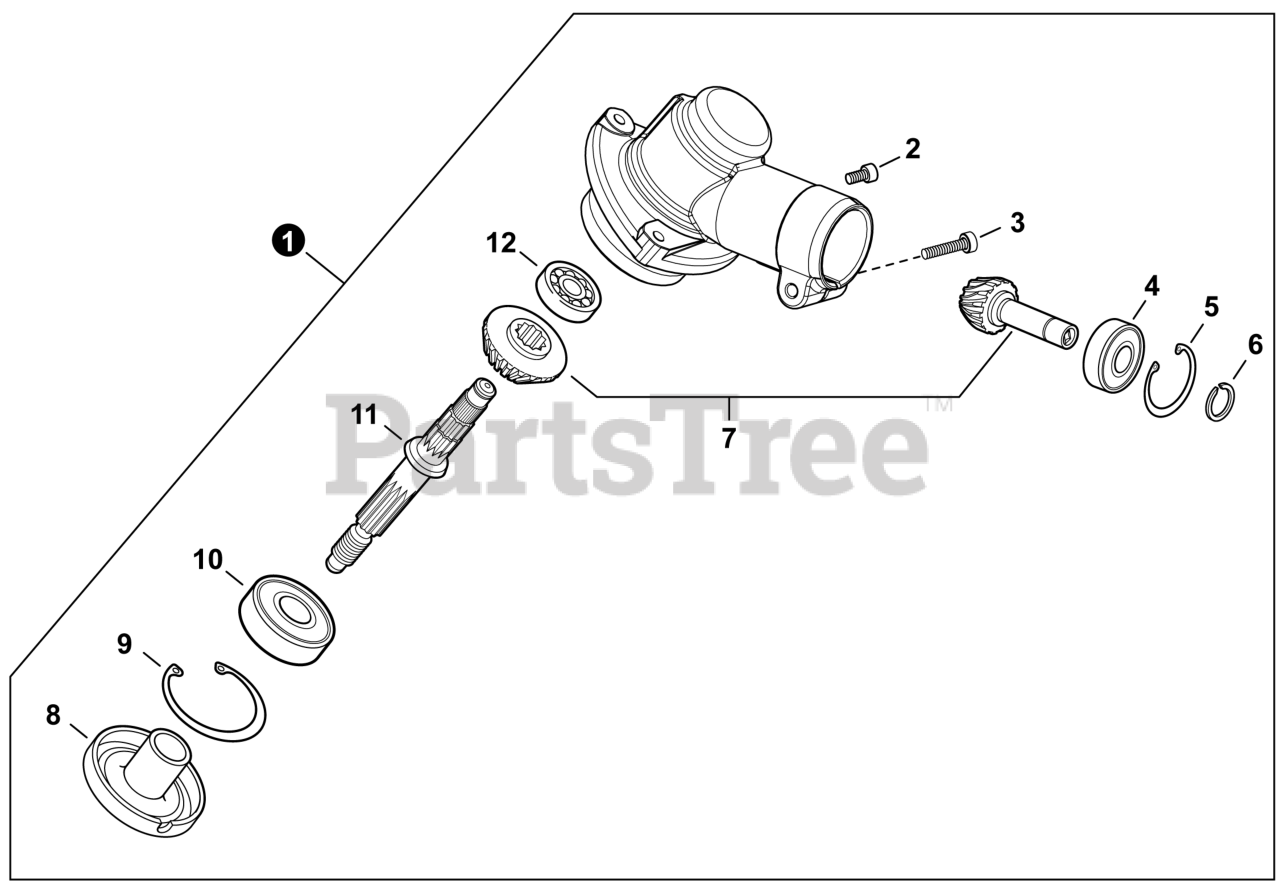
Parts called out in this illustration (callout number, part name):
1	GEAR CASE ASSY
2	BOLT, TORX 5×12
3	BOLT, TORX 5×25
4	BEARING, BALL 609ZA
5	RING, SNAP 24
6	RING, SNAP Ø9
7	GEAR SET
8	PLATE, ADAPTOR - UPPER
9	RING, SNAP Ø32
10	BEARING, BALL 6201 2RS
11	SHAFT, GEAR
12	BEARING, BALL 609A
